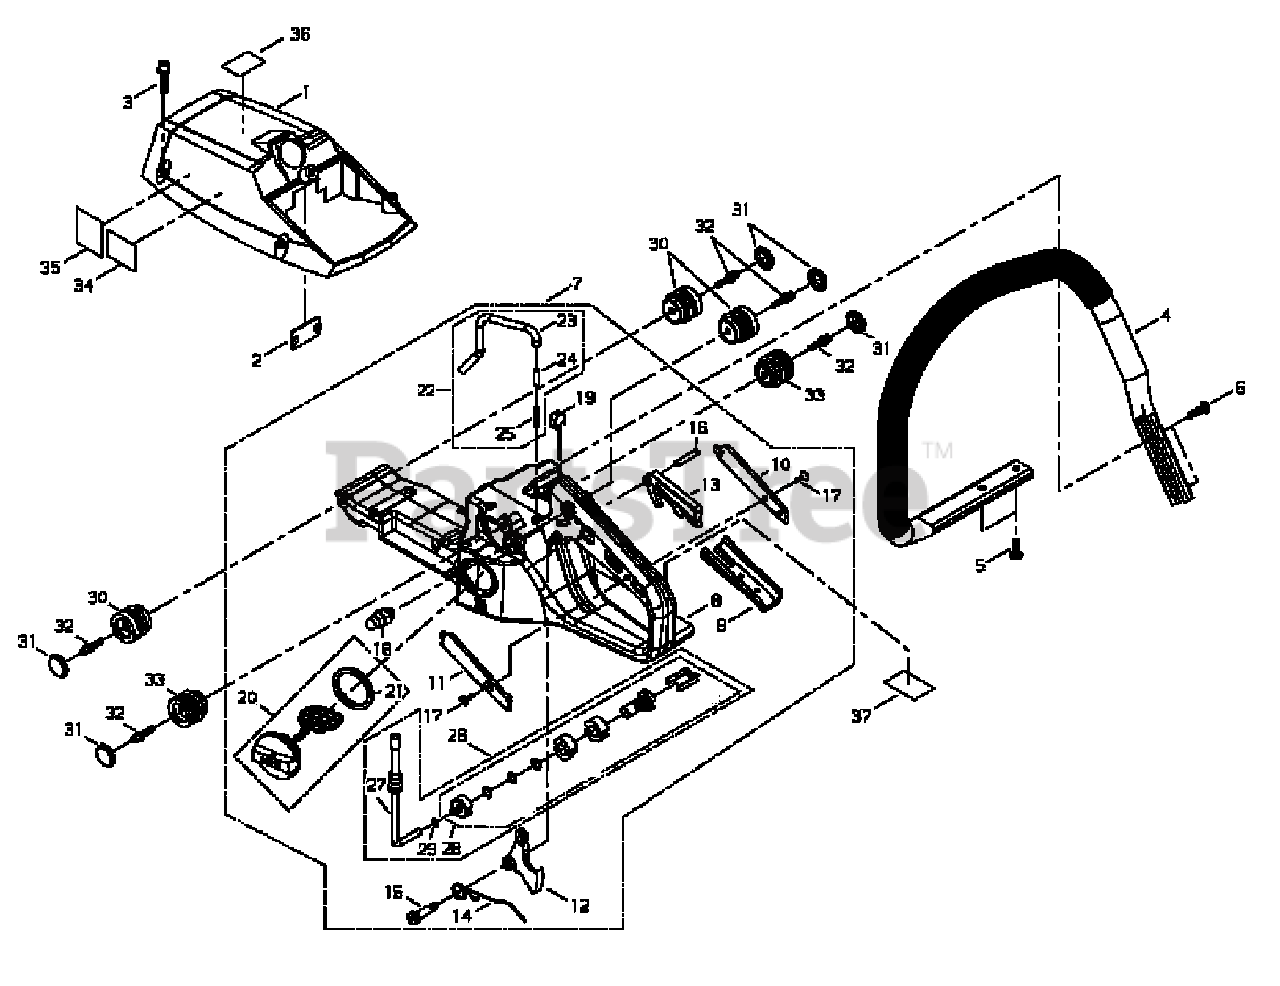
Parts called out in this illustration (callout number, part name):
1	COVER, ENGINE
2	PLUG
3	BOLT
4	HANDLE - FRONT
5	SCREW
6	SCREW - 5X20
7	HANDLE ASSY - REAR
8	HANDLE - REAR
9	BGRIP
10	PLATE - RIGHT
11	PLATE - LEFT
12	TRIGGER, THROTTLE
13	LEVER, LOCK
14	SPRING, LEVER
15	BOLT
16	PIN - SPRING -- 4X25
17	SCREW
18	LOCK, THROTTLE
19	STROPPER R
20	CAP ASSY
21	GASKET, CAP
22	VENT, FUEL TANK
23	PIPE - VENT
24	ELEMENT
25	SPRING
26	FUEL PIPE ASSY
27	PIPE - FUEL
28	FILTER, FUEL
29	CLIP - 6
30	CUSHION
31	CAP, CUSHION
32	BOLT
33	CUSHION
34	LABEL - CAUTION
35	LABEL - CAUTION
36	LABEL - CAUTION
37	LABEL - CAUTION
